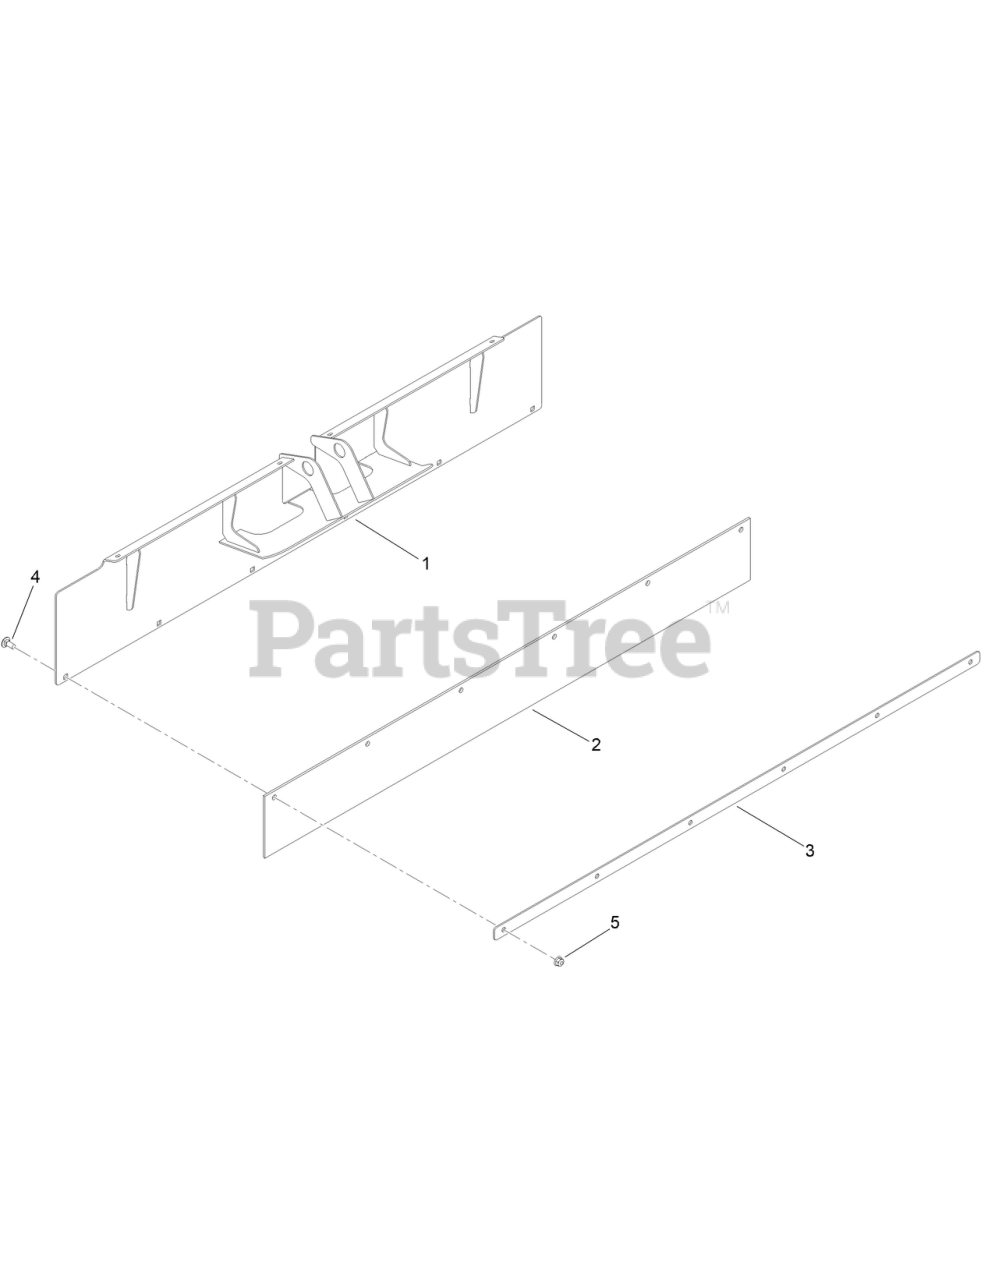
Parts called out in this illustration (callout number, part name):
1	GUARD-REAR
2	FLAP-RUBBER
3	STRIP-BACKER, FLAP
4	SCREW-CARR
5	NUT-HF, NI
